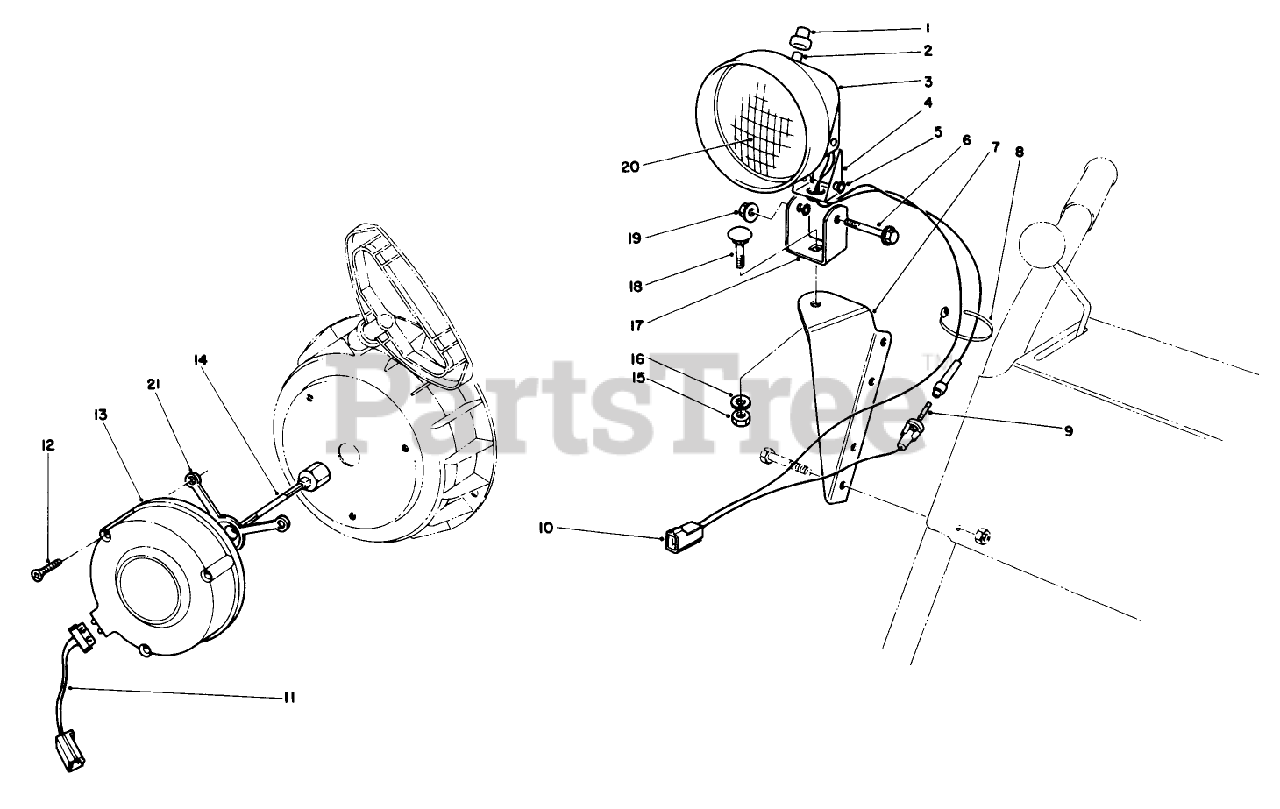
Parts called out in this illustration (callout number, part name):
1	BOOT-SWITCH
2	SWITCH ASM
3	Bucket-Headlamp
4	TO BE DISCONTINED-NOT NEEDED ON PRODUCT
5	WASHER-LOCK
6	SCREW-HH
7	LAMP MOUNT B
8	TIE-CABLE
9	Fuse-7-1/2 Amp.
10	WIRE ASM
11	Connector-Wire
12	SELF TAPPING SCREW
13	Alternator
14	Shaft-Alternator, 3 Inch
15	NUT-HEX
16	WASHER-LOCK
17	BRACKET
18	BOLT-CARR
19	NUT-HF
20	BEAM-SEALED
21	SPACER
